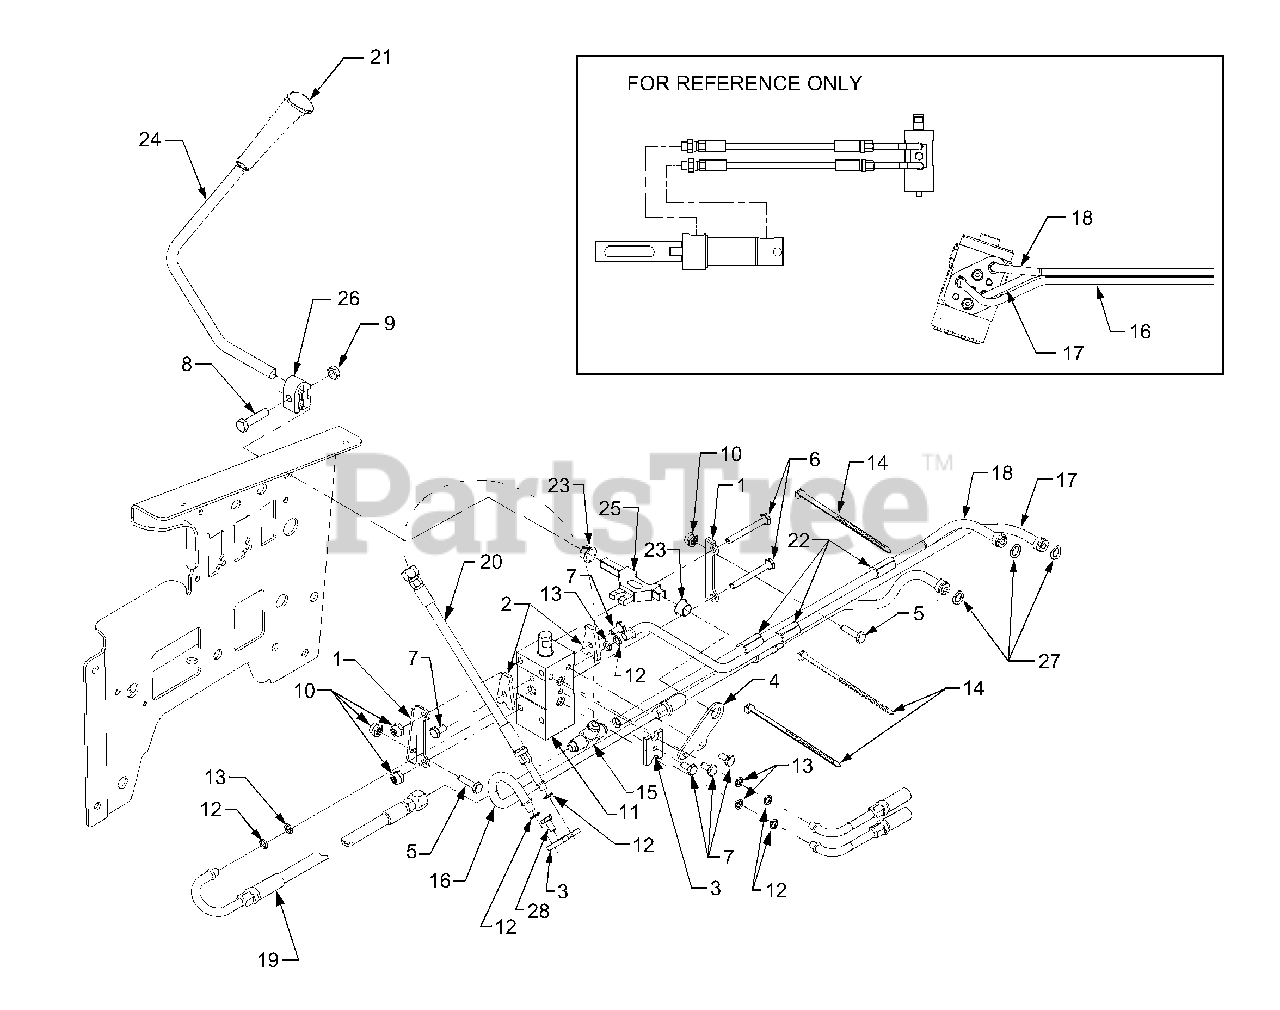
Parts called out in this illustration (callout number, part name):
1	Bracket, Valve Mounting
2	Clamp, Side Valve
3	Clamp, Double Valve
5	Screw, Hex Cap 1/4-20 x 1.0 GR5
6	Screw, Hex Cap 1/4-20 x 2.25 GR5
7	Screw, Hex Cap 1/4-20 x .50 GR5
8	Screw, Hex Cap 5/16-18 x 1.375 GR5
9	Nut, Hex Insert Lock, 5/16-18
10	Nut, Hex Flange Lock, 1/4-20
11	Valve, Hydraulic
12	O-Ring, Backup
13	O-Ring
14	Cable Tie
15	T-Fitting, 9/16-18 Thrd.
16	Tube, Hydraulic (Pump to Strng)
17	Tube, Hydraulic (Aux. from Strng)
18	Tube, Hydraulic (Strng Return)
19	Tube, Hydraulic (Aux Return)
20	Tube, Hydraulic (Return to Pump)
21	Knob, Lift
22	Rubber Spacer
23	Bearing, Nylon Flange
24	Handle, Center Lift Valve
25	Link, Lift
26	Clamp, Handle
27	O-Ring, .426 x .566 x .070
28	Screw, Hex Cap 1/4-20 x .62 GR5
